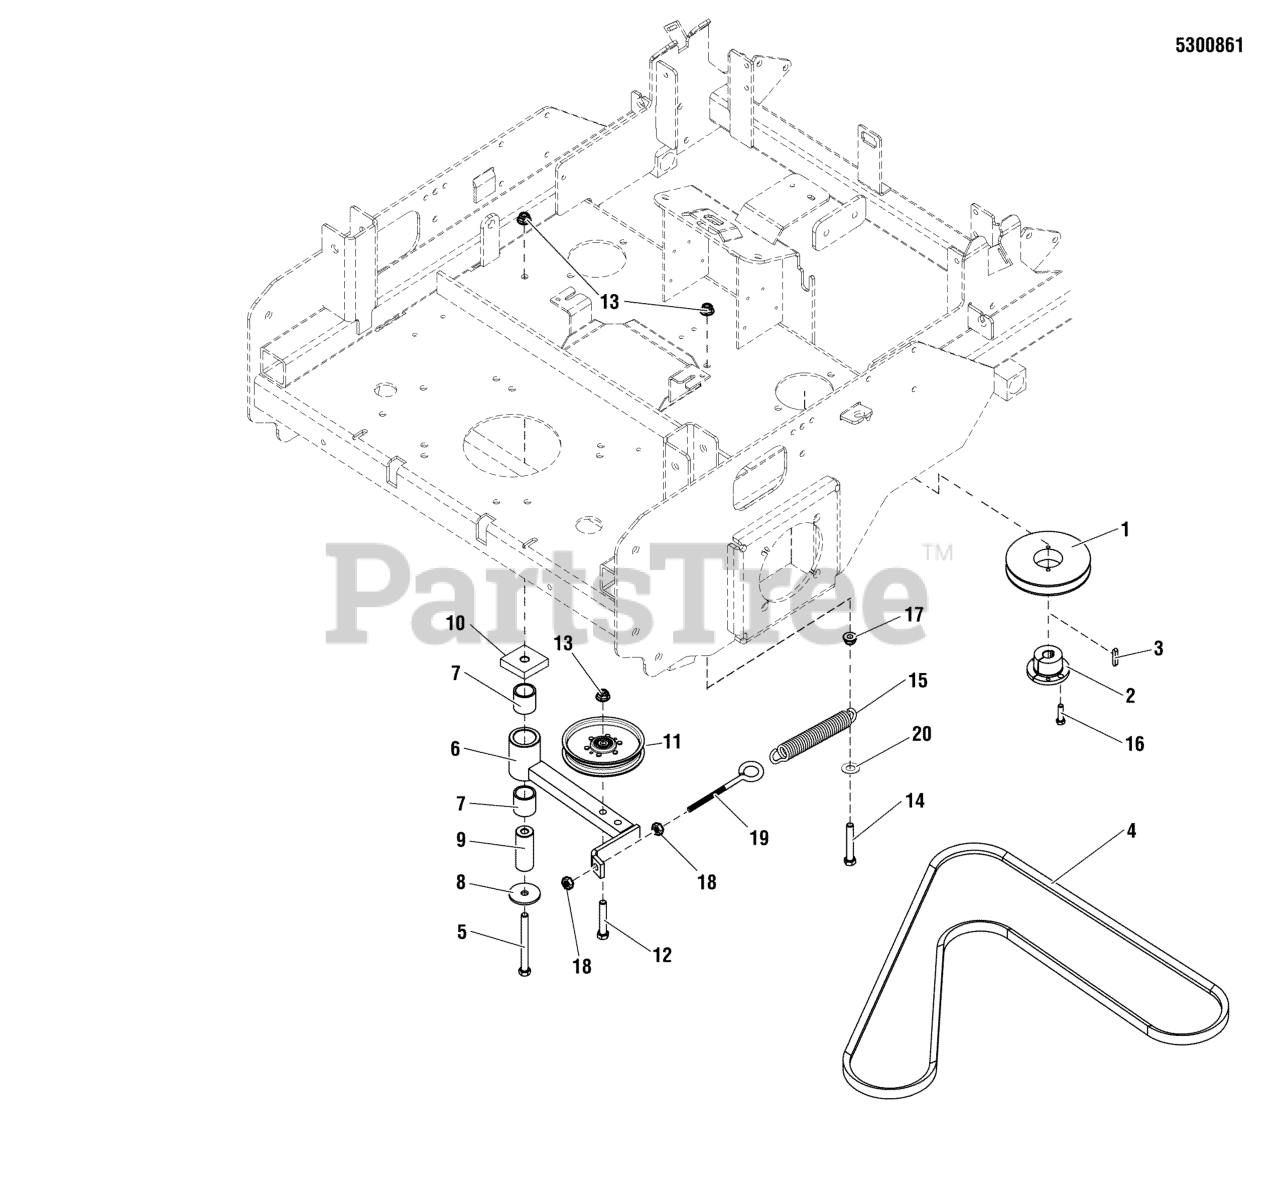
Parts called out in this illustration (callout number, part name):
1	PULLEY, SPLIT STEEL 5.632 OVER BALL
2	BUSHING, TAPERED HUB
3	KEY, 5MM SQ. W/ RADIUS
4	BELT, B SECTION, 69.1" EL
5	BOLT, 3/8-16 X 4" GD5 CZ
6	WELD, IDLER, PUMP DRIVE - RED
7	BUSHING, BRASS, 1.25X1X1.25
8	WASHER, .41 X 1.75 X .14
9	SPACER, .39 X 1.00 X 2.55, SS
10	SPACER, IDLER PIVOT
11	PULLEY, FLAT IDLER, 5" W/KOYO
12	BOLT, 3/8-16 X 2-1/4" GD5 CZ
13	NUT, 3/8-16 HEX NYLOCK FLANGE
14	BOLT, 3/8-16 X 3" GD5 CZ
15	SPRING, EXTENSION, SWIVEL END
16	BOLT, 1/4-20 X 1" GD5 CZ
17	NUT, 3/8-16 HEX SERRATED FLANGE
18	NUT, 3/8-16 HEX
19	EYE BOLT, 3/8-16 X 8", 1" EYE
20	WASHER, 3/8 SAE
21	SET SCREW, 5/16-18 X 3/8, KNURL, W/PATCH
